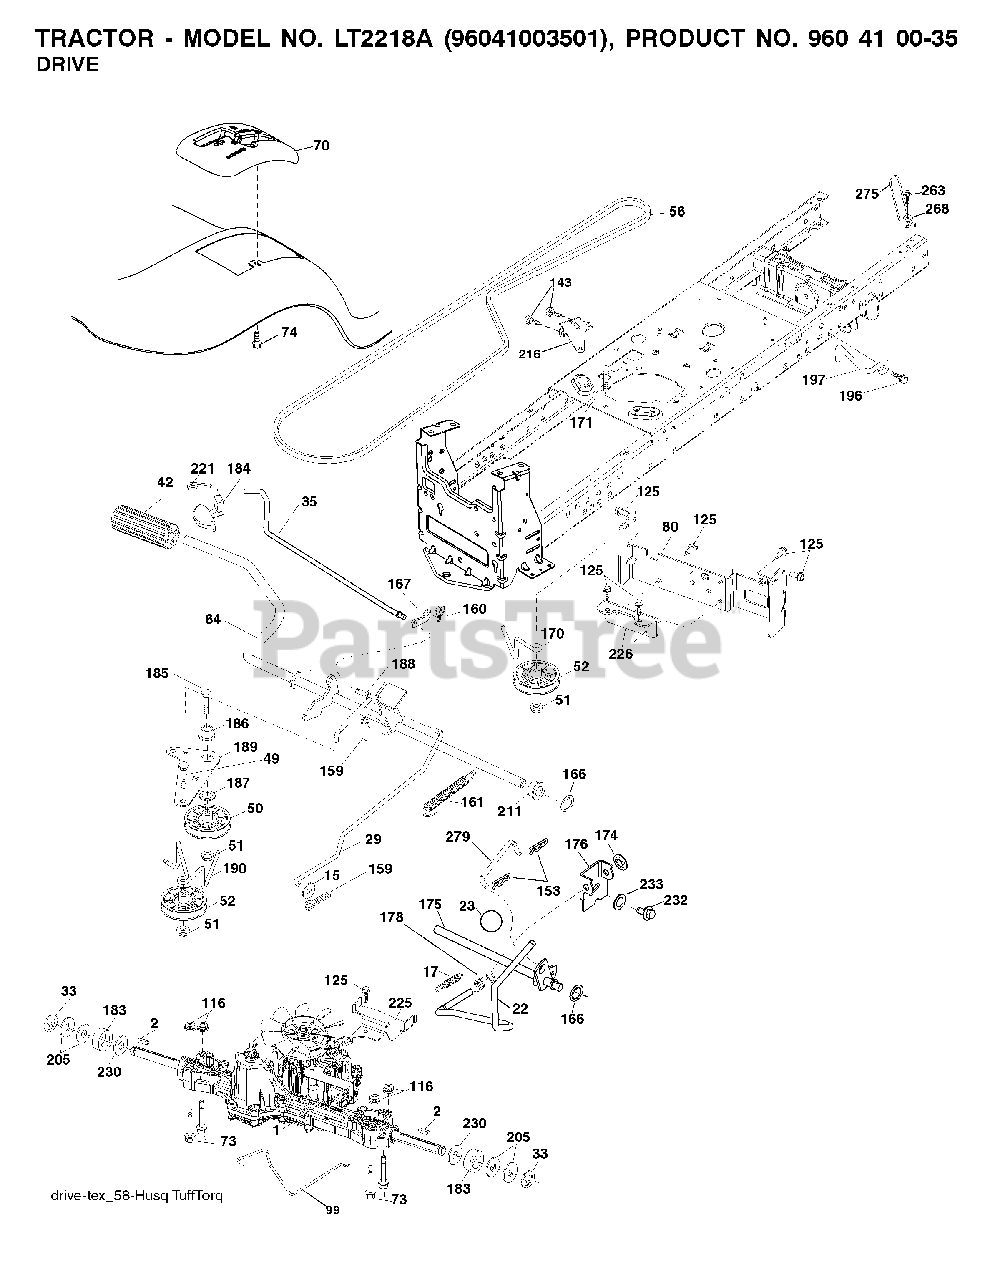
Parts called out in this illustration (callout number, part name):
1	TRANSAXLE.K46A
2	SQUARE KEY
17	SPRING.BRAKE.K46.GREEN
22	ROD.SHIFT.FENDER.TLT.2006
23	PISTOL KNOB
29	ROD.BRAKE.K46
33	E-RING LT
35	ROD.BRKAE.PARKING.STEALTH
42	PEDAL COVER T
49	BOLT
50	IDLER.FLAT.910.OFFSET
51	NUT LOCK FLG 3/8-16 UNC
52	IDLER.V-GROOVE.910.OFFSET
64	SHAFT.ASM.PEDAL.BRAKE.
70	CONSOLE.SHIFT.STL.HYD.BLACK
73	BOLT HEX 5/16-18 GR 5
74	SCREW.HI-LO.CONSOLE
80	STRAP TORQUE
99	ROD ASM BYPASS
116	NUT LOCK HEX FLANGE 5/16-18
125	SCREW
153	RETAINER M
159	COTTER PIN
160	RETAINER CLIP
161	SPRING.RETURN.CLUTCH.2006
166	NUT.PUSH.625.2006
167	LATCH.BRAKE.SPRING
170	KEEPER.V-IDLER.CENTER.
171	BOLT
174	NUT.PUSH.500.2006
175	SHAFT ASM SHIFT
176	ARM.CLEVIS.ROD.SHIFT
178	SPRING.SHIFT.GT2006
183	SPACER AXLE
184	HANDLE.PRKG.BRAKE.STLTH.TX.RED
186	SPACER.RETAINER
187	WASHER 12/32X2X10GA
188	LINK.CLUTCH.GROUND.DRIVE
189	BELLCRANK.GROUND.DRIVE.TEX.
190	KEEPER.BELLCRANK.DRIVE
196	SCREW 3/8-16X1
197	LINK.CLUTCH.ANIT-ROTAT
211	BUSHING.SHAFT.BRAKE.HAND
216	BRACKET.PULLEY.IDLER.W/TEX
221	RETAINER.SPRING.CLIP.H
225	KEEPER.BELT.TRANSAXLE.K46
226	BRACKET.MOUNT.TORQUE.K46.TLT
230	WASHER.HARDENED
232	BOLT FIN HEX 7/16-14 X 1
233	WASHER SERRATED
263	SCREW, 3/8-16X3/4
268	WASHER
279	LINK SHIFT
